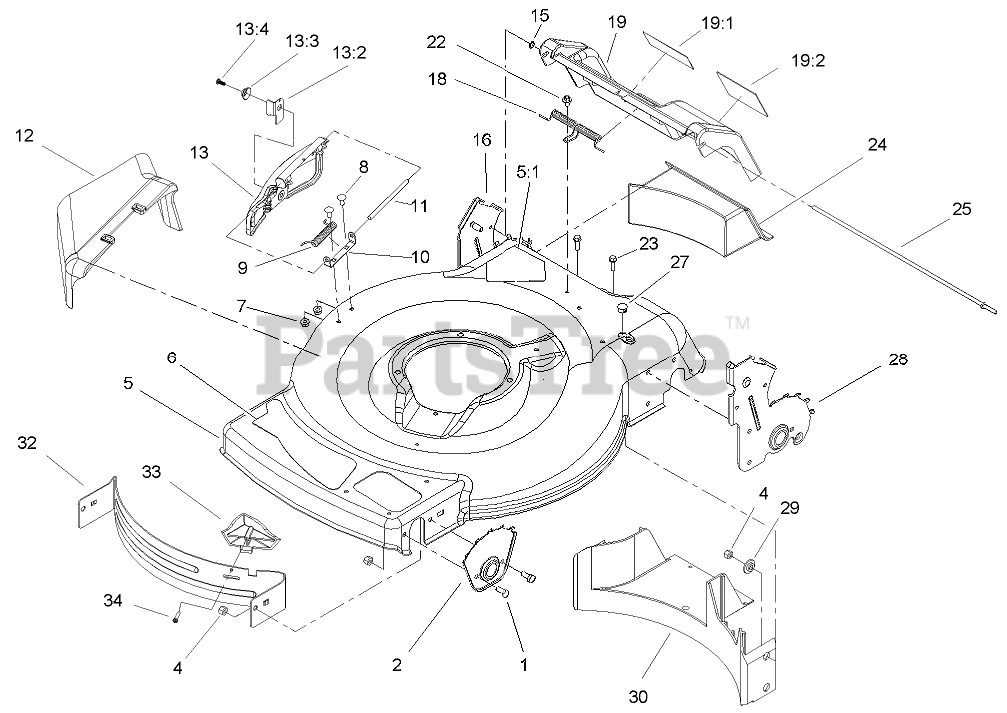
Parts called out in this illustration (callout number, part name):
1	SCREW-HH
2	Plate-HOC, Front
4	NUT-LOCK, NI
5	HOUSING
5:1	DECAL-DANGER
6	Decal-Deck
7	NUT-HHF
8	SCREW-CARR
9	SPRING-TORSION
10	BRACKET-COVER
11	ROD-COVER
12	CHUTE-DISCHARGE, SIDE
13	DISCHARGE DOOR ASM
13:2	LATCH-DOOR
13:3	CAP-DOOR
13:4	SCREW-PLASTITE
15	NUT-PUSH
16	RH REAR HOC PLATE ASM
18	Spring-Door, Rear
19	REAR DOOR ASM
19:1	DECAL-WARNING
19:2	DECAL-WARNING
22	SCREW AND WASHER ASM
23	SCREW-HWH
24	Plug-Discharge, Rear
25	Rod-Pivot, Rear Door
27	Plug-Dome
28	LH REAR HOC PLATE ASM
29	Washer-Stepped
30	Baffle-Rear
32	BAFFLE-FRONT
33	KICKER-FRONT
34	SCREW-PPH
